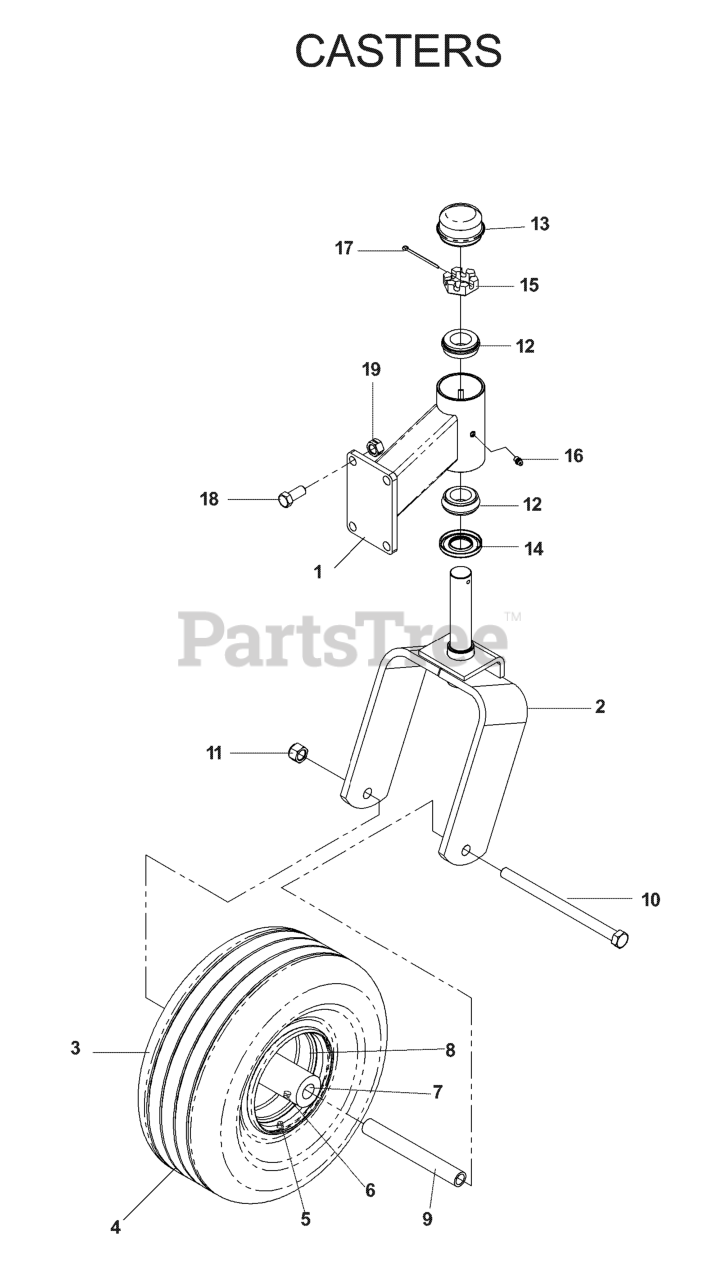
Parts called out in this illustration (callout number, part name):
1	CASTER ARM, ORG
2	CASTER YOKE ORANGE
3	TIRE.ASSEM.13X5-6.SMOOTH.SILVE
4	TIRE - FRONT
5	VALVE STEM TR-412
6	ZERK 1/8 NPT
7	BEARING RETAINER
8	RIM
9	SPACER, CASTER
10	SCREW 1/2C X 7 1/2 HEX CAP
11	NUT 1/2-13 HEX NYLOC ZD
12	TAPERED ROLLER BRG
13	GREASE CAP
15	NUT 1"C HEX SLOTTED
17	COTTER PIN 1/8 X 2
18	HCS 7/16-14 X 1 GR 5 ZD
19	NUT 7/16C CENTERLOCK
